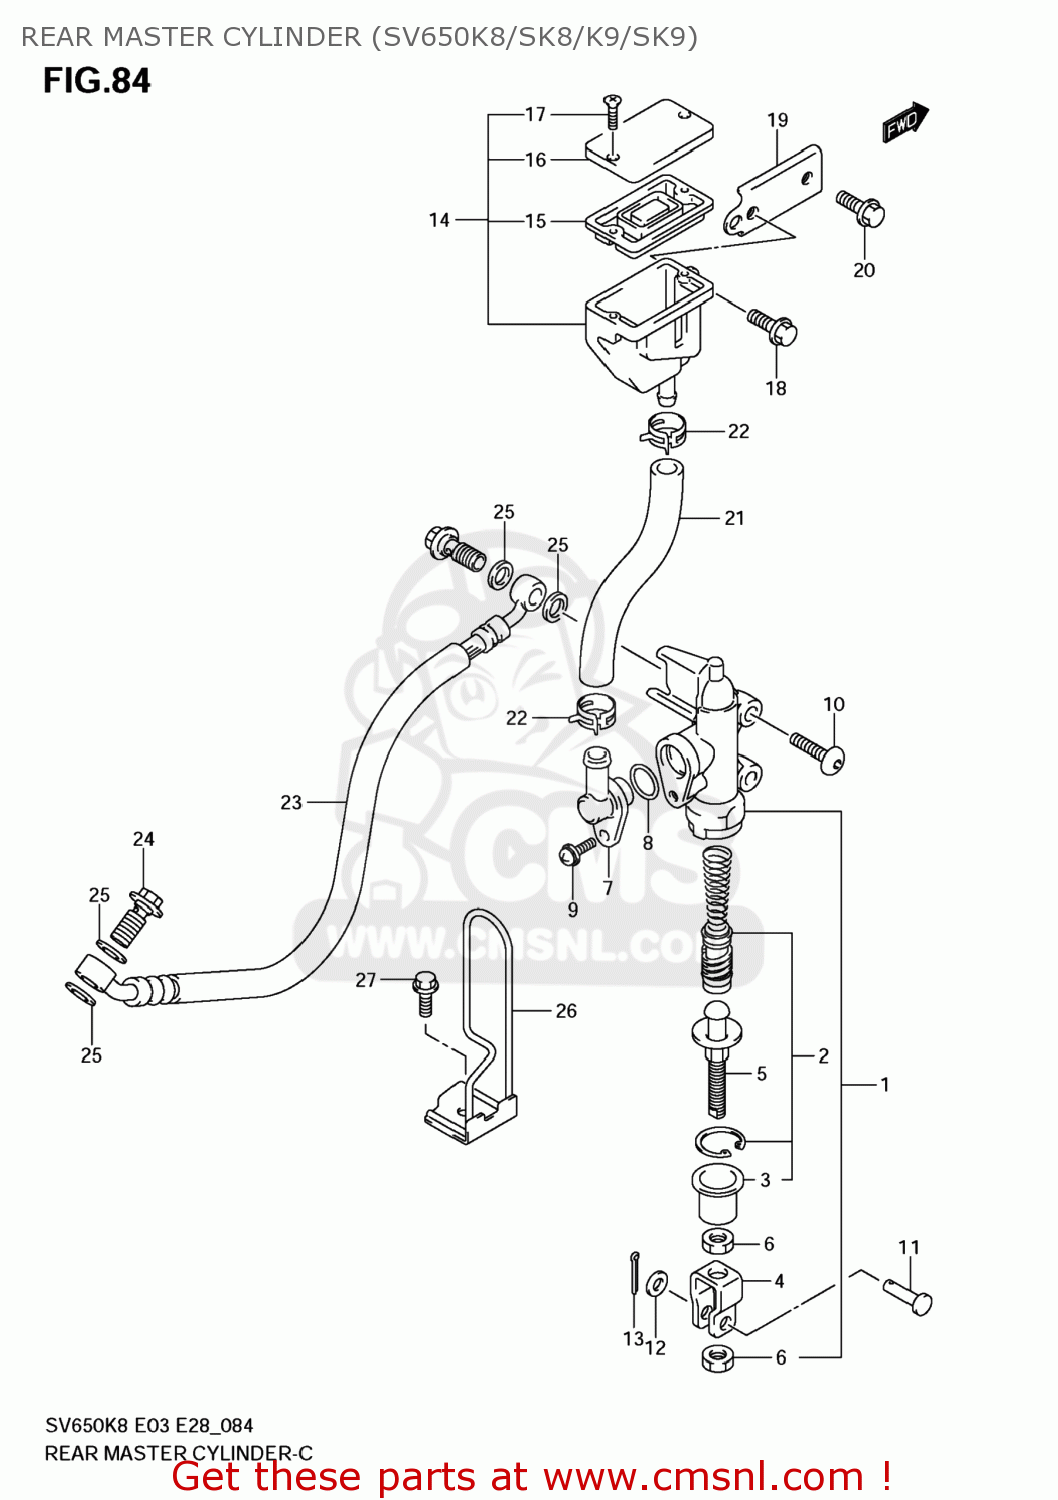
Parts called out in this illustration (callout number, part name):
1	CYLINDER ASSY,RR MASTER
2	PISTON/CUP SET
3	BOOT
4	YOKE
5	ROD,PUSH
6	NUT
7	CONNECTOR
8	O RING
9	SCREW
10	SCREW(6X20)
11	PIN(6X18.2)
12	WASHER
13	PIN
14	TANK ASSY,RR RESERVOIR
15	DIAPHRAGM
16	CAP
17	SCREW
18	BOLT(6X12)
19	BRACKET,RR RESERVOIR TANK
20	BOLT
21	HOSE,RR RESERVOIR TANK
22	CLIP
23	HOSE,RR BRAKE
24	BOLT UNION
25	WASHER(10X15X1.5)
26	GUIDE,RR BRAKE HOSE NO.1
27	BOLT
